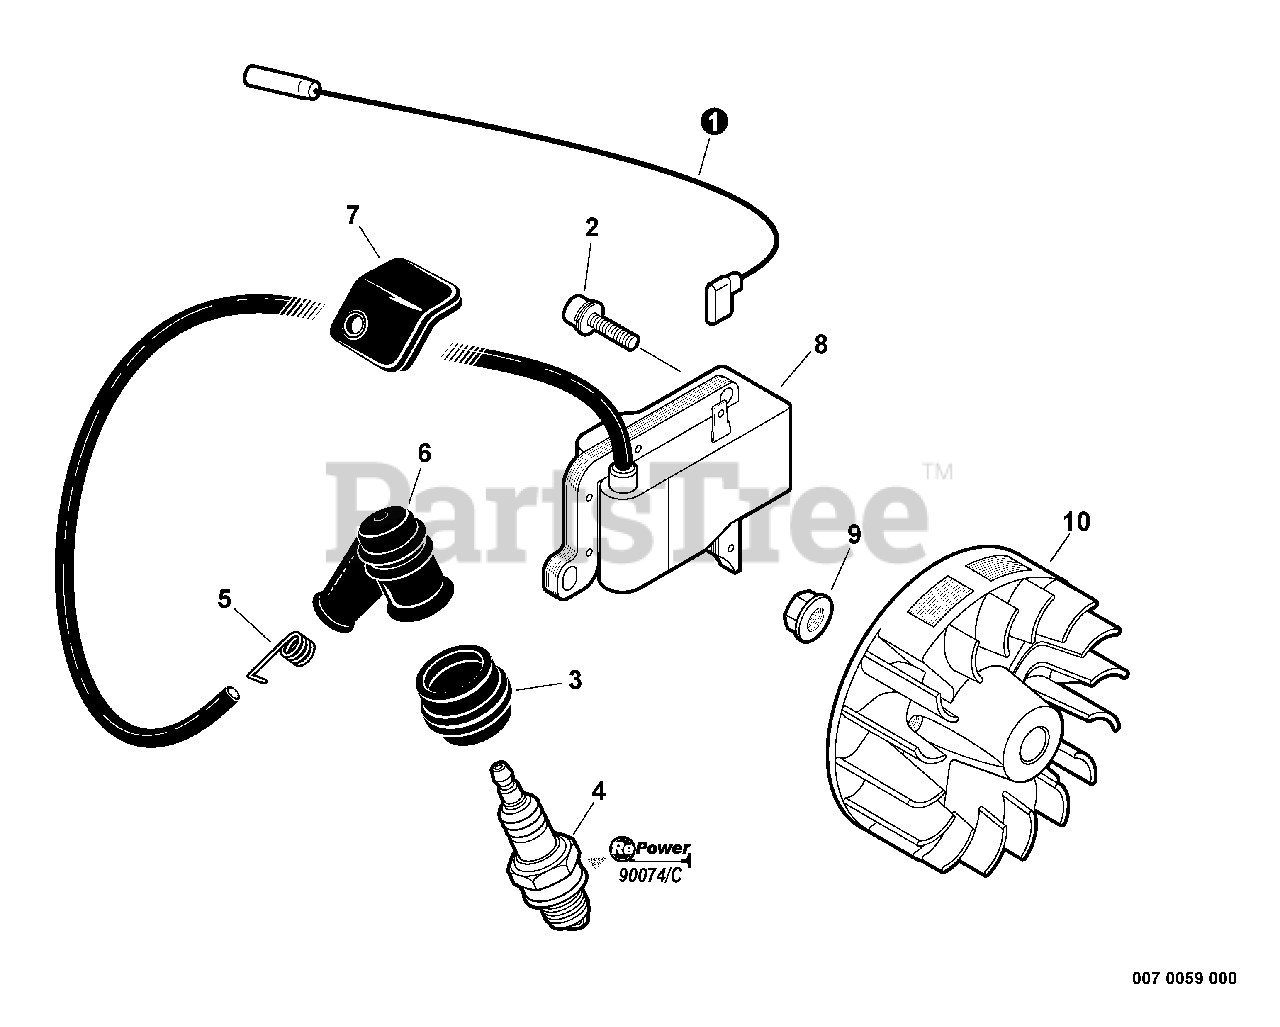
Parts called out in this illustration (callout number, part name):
1	LEAD - IGNITION
2	SCREW - 5X16
3	COVER, SPARK PLUG CAP
4	SPARK PLUG -- BPM-8Y
4	SPARK PLUG -- BPMR-8Y
5	TERMINAL, SPARK PLUG CAP
6	CAP, SPARK PLUG
7	COVER, DUST
8	COIL, IGNITION
9	NUT - 8 -- FLANGE
10	FLYWHEEL
11	RePower TUNE-UP KIT
